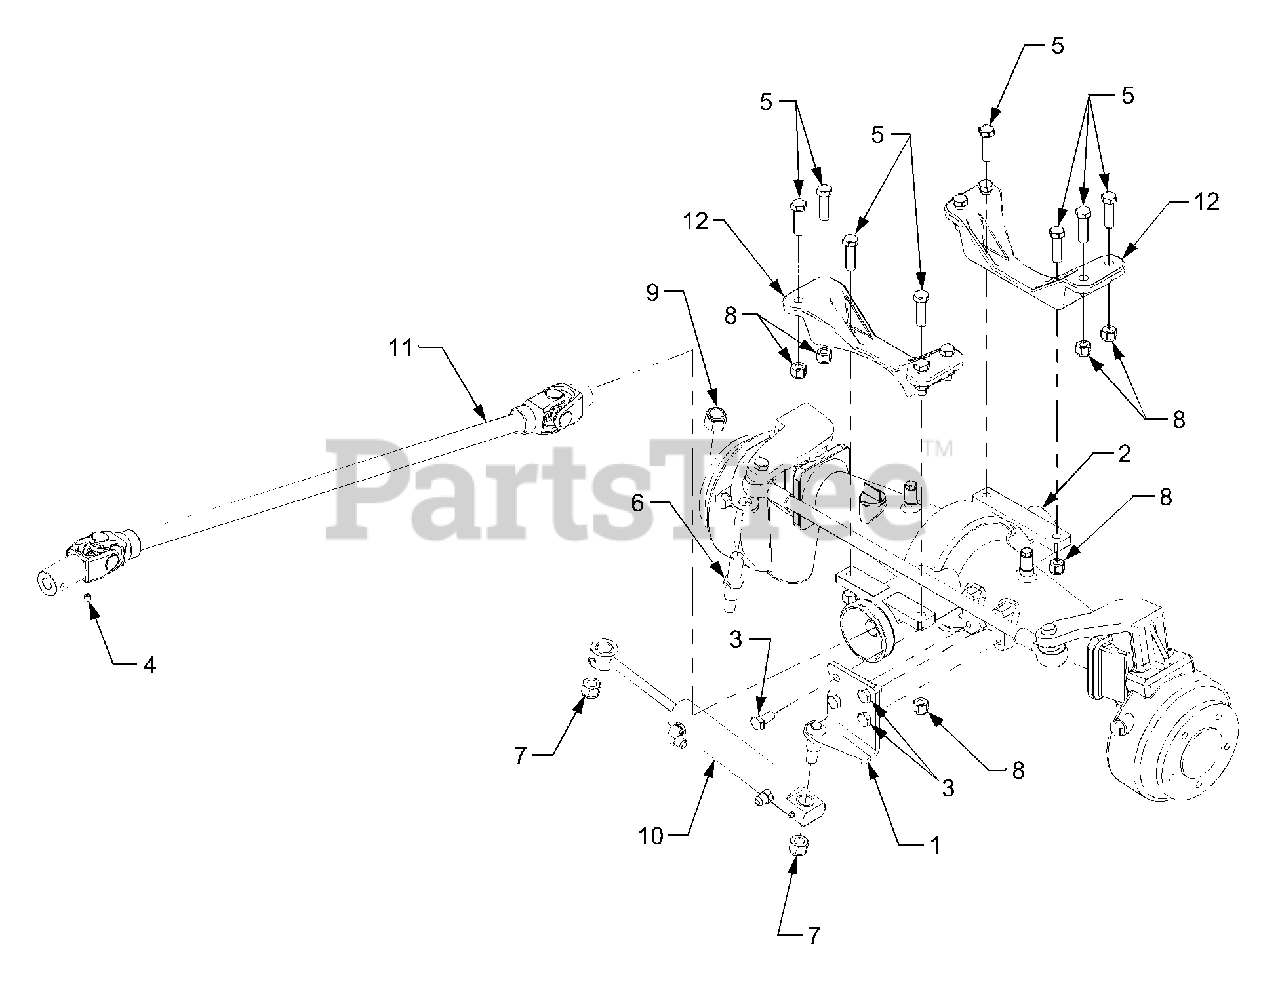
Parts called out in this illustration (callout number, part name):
1	Plate, Steering Cylinder Mtg
2	Axle Assembly, Front 4WD
3	Screw, Hex Cap, M12-1.75 x 25.GR8
4	Screw, Set, 5/16-18 x 3/8
5	Screw, Hex Cap, 1/2-13 x 1.75 GR5
6	Stud, Cylinder Mtg.
7	Nut, Hex Nylon Insert Lock 5/8-11 GR5
8	Nut, Hex Nylon Insert Lock 1/2-13 GR8
9	Nut, Hex Lock, 3/4-10
10	Cylinder, Steering
11	Shaft, Drive 4WD
12	Bracket, Axle Mtg.
